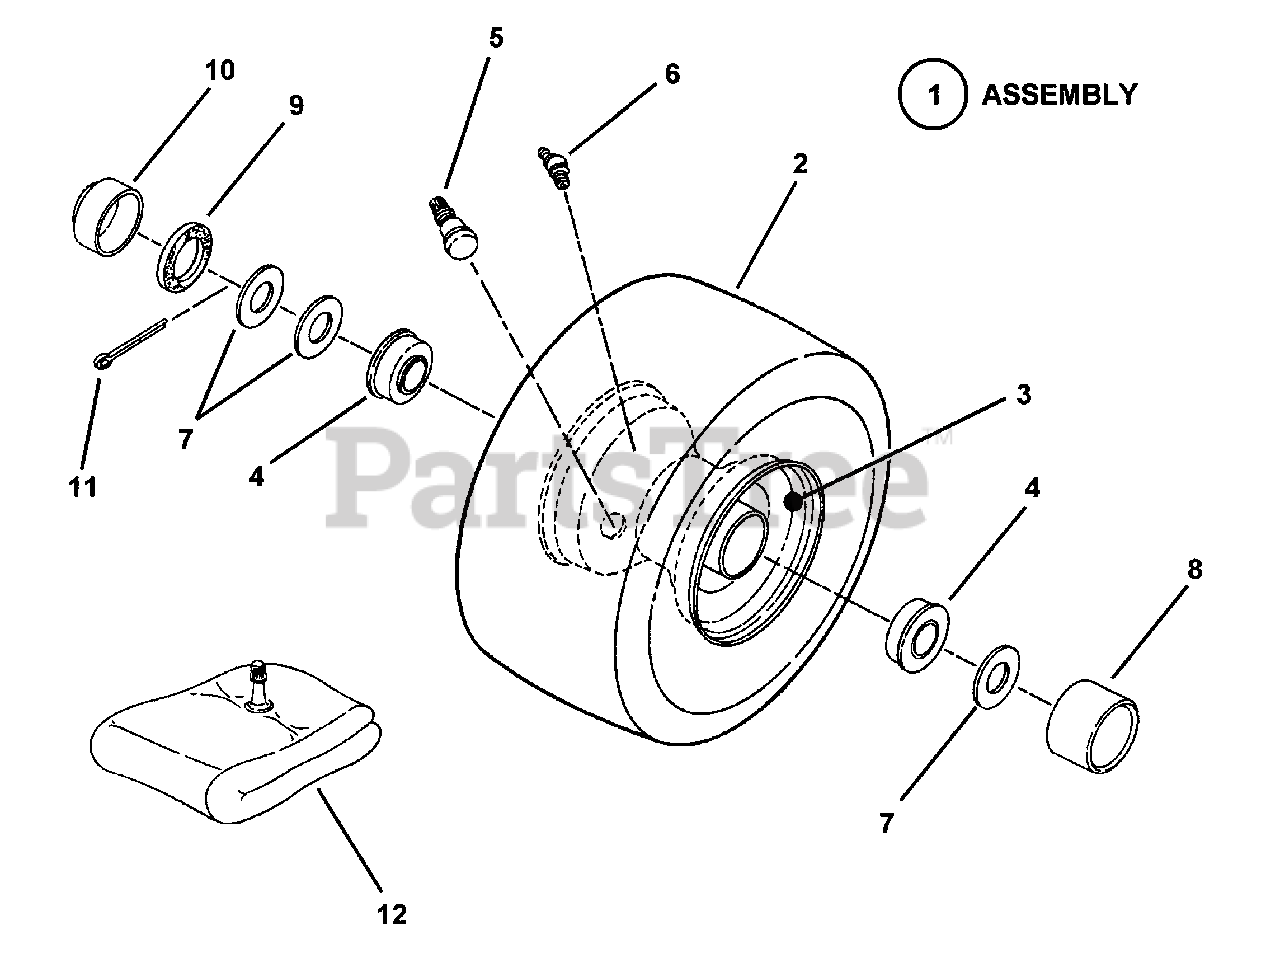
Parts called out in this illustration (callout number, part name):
1	ASSEMBLY, Front Tire & Rim (11.0")
2	TIRE, Pneumatic 11.0 x 4.0 x 4
3	RIM
4	BEARING, Ball
5	VALVE, Air (Snap-In)
6	FITTING Lube
7	WASHER
8	CAP, Hub
9	SEAL, Felt
10	CAP, Dust
11	COTTER-PIN, 5/32 x 1"
12	TUBE, Inner
